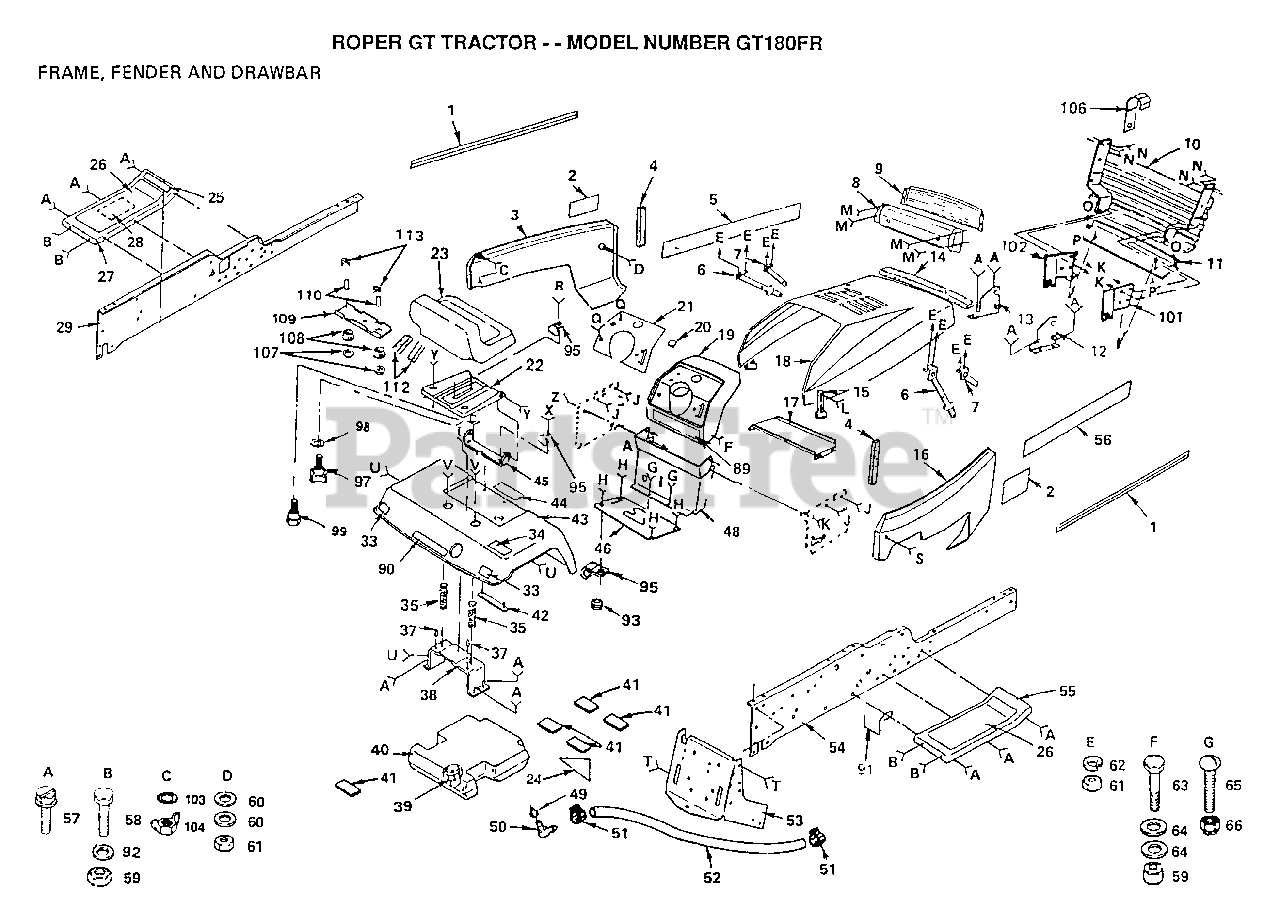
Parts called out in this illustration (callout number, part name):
4	FOAM STRIP T
9	LENS LT
12	SUPPORT RH YTH
13	SUPPORT LH YTH
15	HOOD LATCH T
20	PLUG-DASH T
25	DECAL T
27	FOOTREST LH YT
28	DECAL T
33	REFLECTOR-TAIL YT
34	SCREW
37	NUT-PUSH YT
41	PAD-SPACER LT
44	DECAL
46	CVR SHAFT GATE
48	DASH ASSEMBLY
49	BUSHING OUTLET T
50	FUEL TANK STEM GT
57	SCREW
60	WASHER PM
63	BOLT
64	WASHER
65	SCREW
91	BELT RETAINER GT
92	WASHER
93	GROMMET T
97	"KNOB 1/2"" YT"
98	WASHER
101	SUPPORT LH YTH
103	LOCKWASHER GT
106	CLIP GT
107	NUT T
108	BUSHING
109	BRKT SWITCH
110	SPACER SPLIT
112	STRIP FORM
113	SPRING
